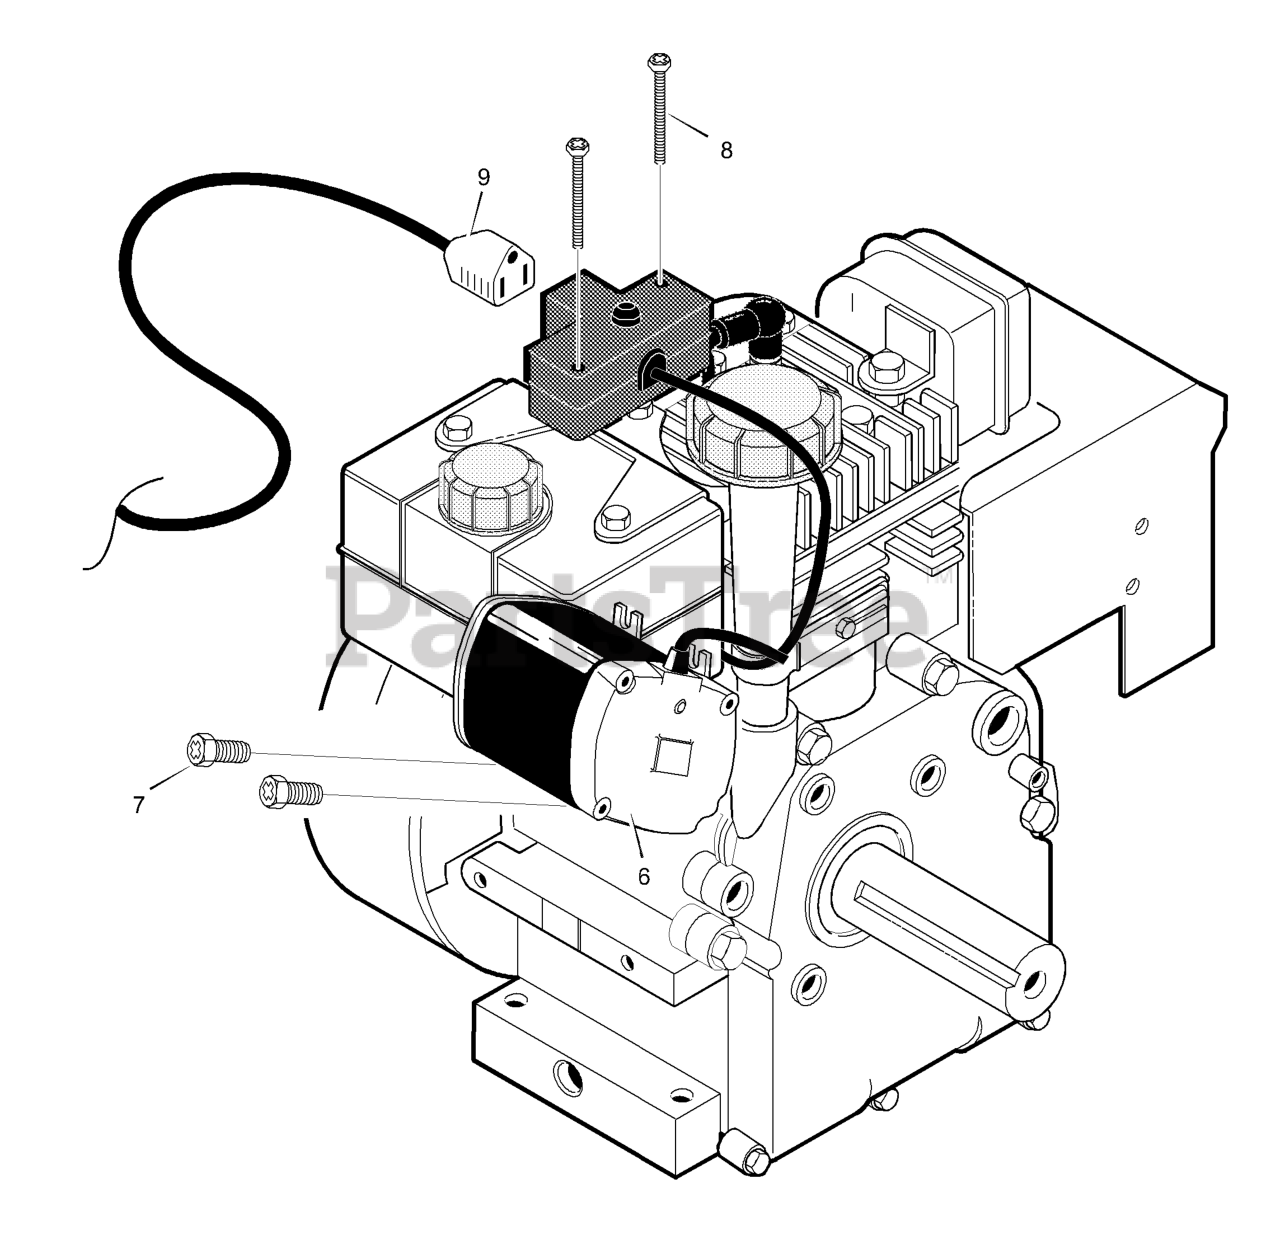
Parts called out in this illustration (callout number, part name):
6	MOTOR, STARTER
8	SCREW
9	CORD, STARTER 220 V
